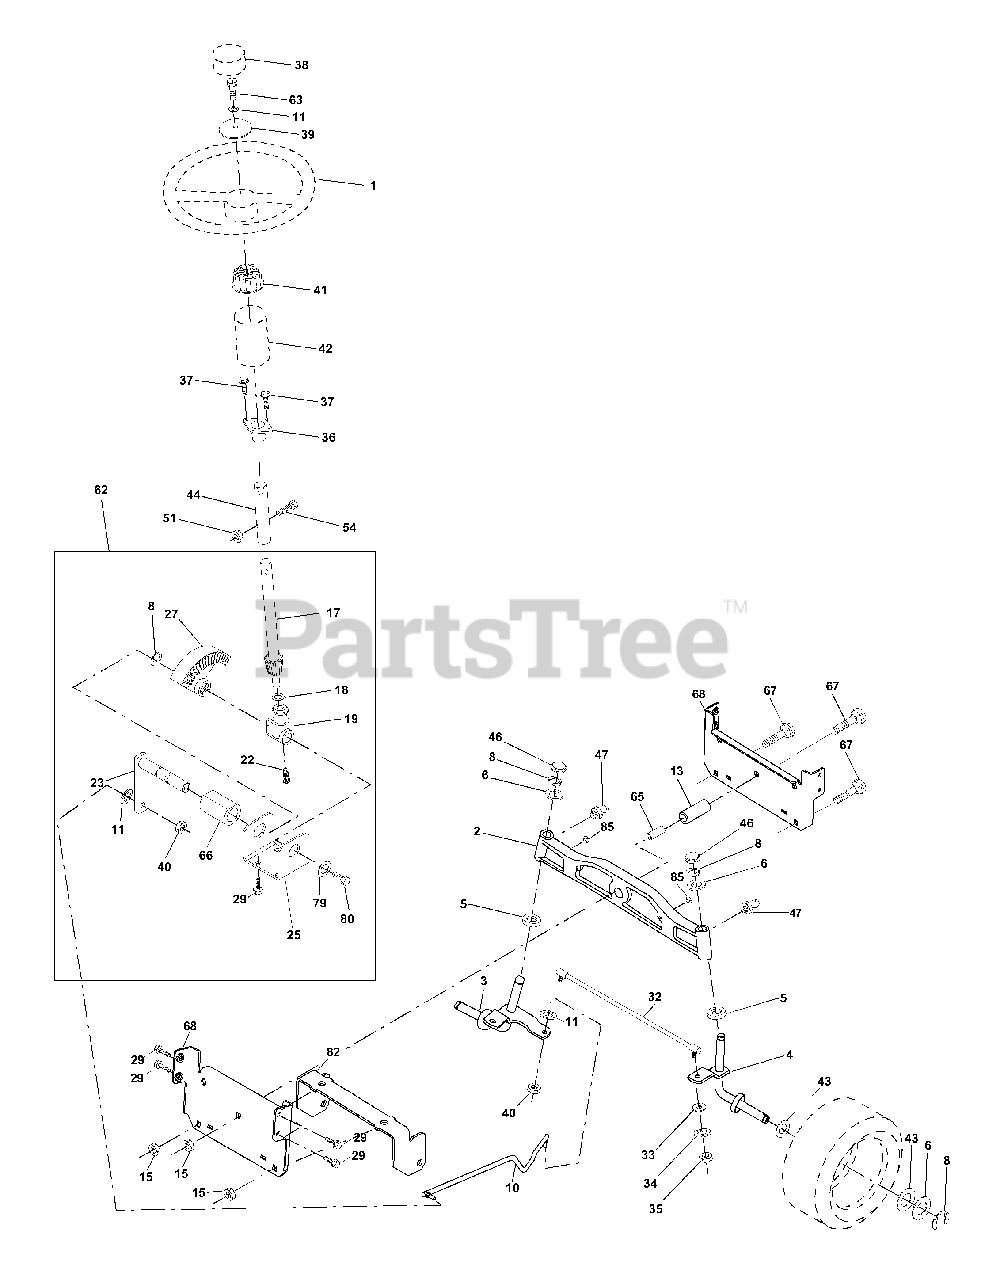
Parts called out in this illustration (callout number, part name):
1	Steering Wheel
2	Axle, Front
3	Spindle, L.H.
4	Spindle, R.H.
5	Bearing, Thrust
6	Washer 25/32 x 1-5/8 x 16 Gauge
10	Link, Drag
11	Washer, Lock 3/8
12	Nut, Hex, Jam, Top Lock 1/2-20 UNF
13	Spacer Brg Axle front
15	Nut Hex flange Lock
17	Shaft, Steering
19	Shaft, Support
22	Screw Hex Wsh hd Torx
23	Shaft, Pitman
25	Bracket, Steering
27	Gear, Sector
29	Screw, 3/8-16 x 3/4
33	Washer 11/32 x 3/4 x 16 Ga.
34	Washer Lock Hvy Helical 5/16
35	Nut Crown Lock 5/16-24
36	Bushing Steering
37	Screw TT #10-32 X 5 x 3/8 Flange
38	Insert, Steering Wheel
40	Nut, Lock Center 3/8-24 Unf Blk
41	Adapter, Steering Wheel
42	Boot Steering Dash P/L Mtl
43	Washer, 25/32 x 1-1/4 x 16 Gauge
44	Extension Steering Non-Adjust
46	Spindle, Cap
47	Grease Zerk
51	Nut Lock Hex w/Ins 5/16-18 Unc
54	Bolt Fin Hex 5/16-18 Unc x 1-1/4
62	Kit Steering Asm Service
63	Bolt Fin Hex 3/8-16 Unc x 1 Gr. 5
65	Spacer Brace Axle
66	Bearing Arm Pittman
67	Bolt Rdhd Sq 3/8-16 x 2-1/4
68	Brace Brace Axle
79	Washer 13/32 x 1-1/4 x 12 Ga
80	Bolt Hex Nylon 3/8-16 x 3/4
82	Bracket Susp Chassis Front 15"
85	Fastner Christmas Tree
